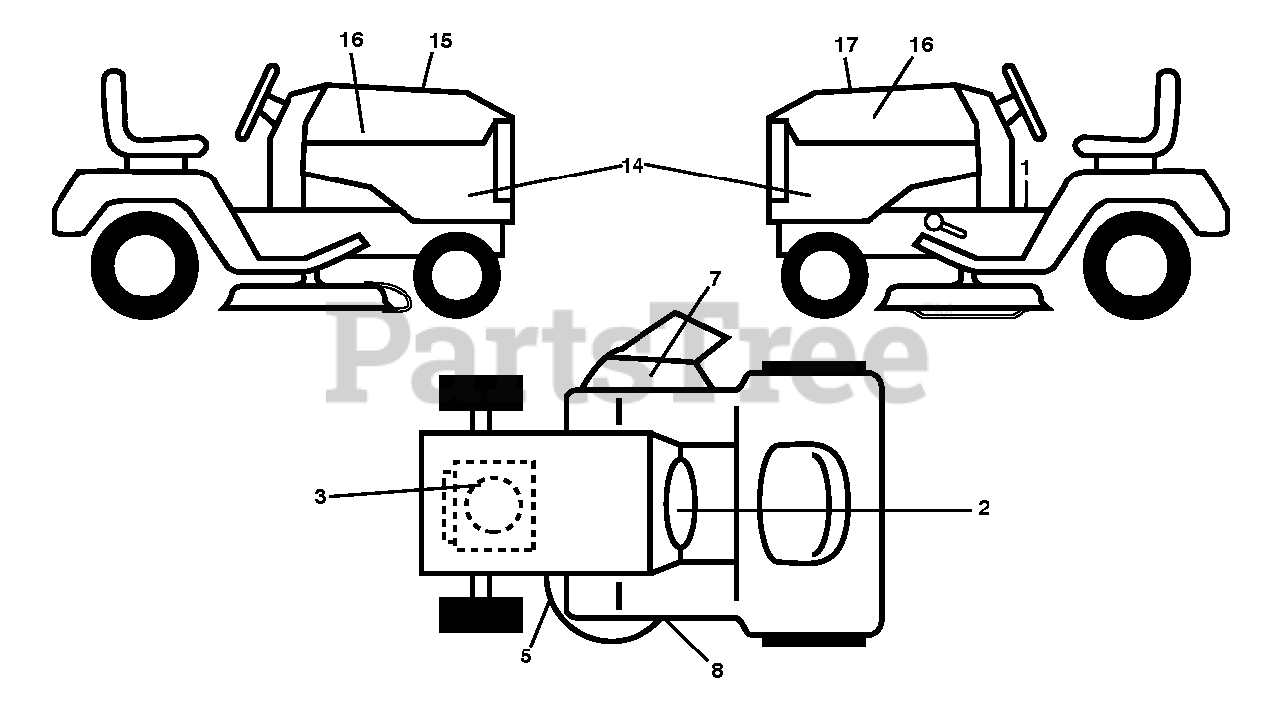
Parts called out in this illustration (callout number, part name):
1	DECAL TRACTOR LOWES DECAL DECA
2	Warning Decal, Spark Arrest
3	DECAL.ENG.BS.INTK.24HP.382016
5	DECAL.MOWER.CAUTION.TENSION.AR
7	DECAL, DECK DEFLECTOR, WARNING
8	DECAL.MOWER.SCH.48/54.PREM
14	DECAL PANEL SD
15	DECAL.WARNING.CUST.RESP.E85.
16	DECAL.BADGE.170MM.TEXTLOGO.
17	Decal, Replacement BSM44 INTK TLW
